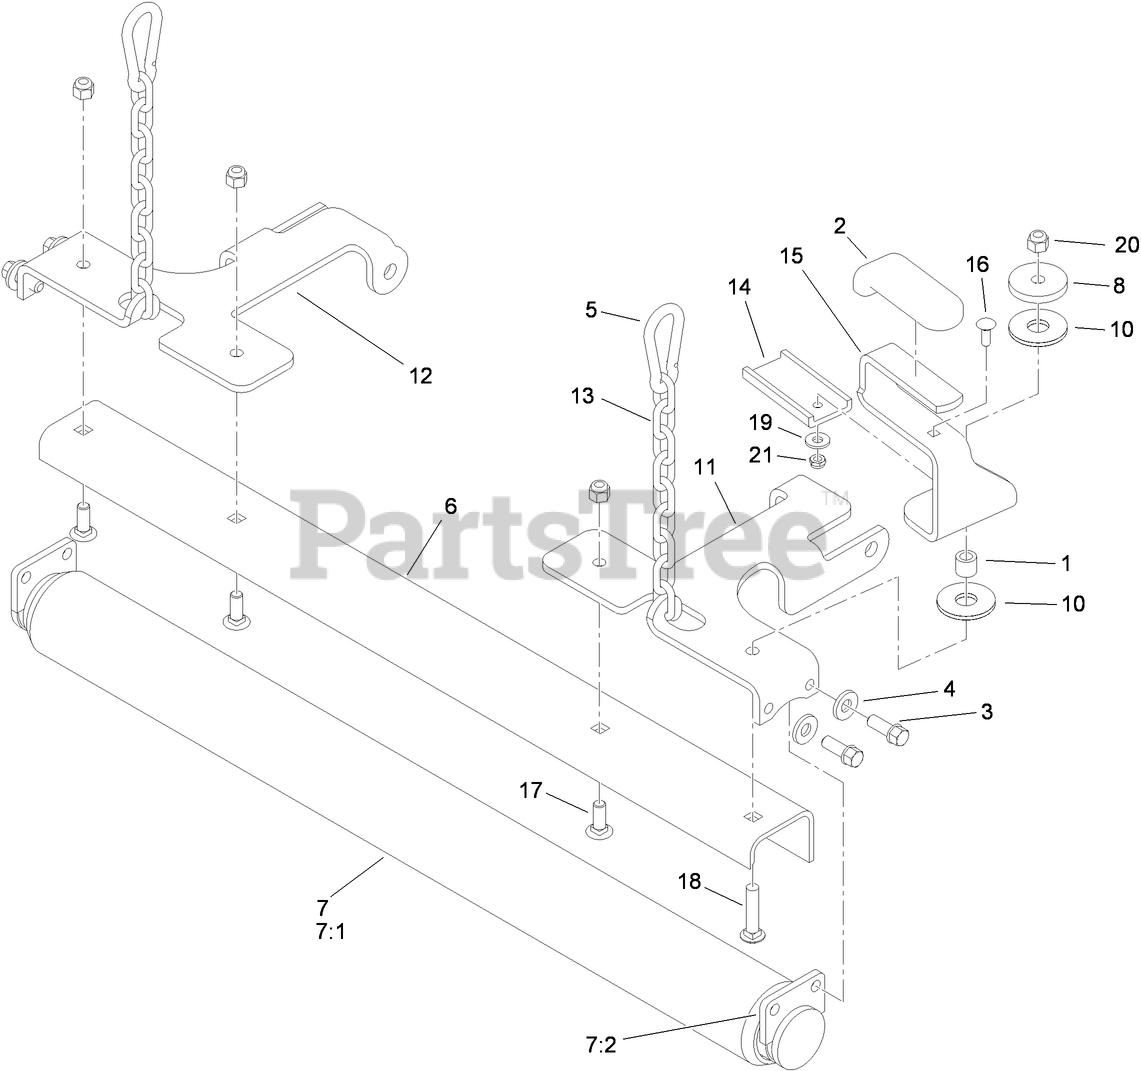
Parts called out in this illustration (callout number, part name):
1	SPACER
2	GRIP-LEVER
3	SCREW-HWH
4	WASHER-BELLEVILLE
5	LINK-SNAP
6	SCRAPER-ROLLER
7	ROLLER ASM
7:1	ROLLER-STRIPER
7:2	HUB ASM
8	WASHER-PLAIN
10	WASHER-FRICTION, COMPOSITE
11	MOUNT-ROLLER, RH
12	MOUNT-ROLLER, LH
13	CHAIN-LINK, STRAIGHT
14	SLIDE-PLASTIC
15	LEVER-ROLLER
16	BOLT-CARR
17	SCREW-CARR
18	SCREW-CARR
19	WASHER-FLAT
20	NUT-LOCK, NI
21	NUT-LOCK, NI
